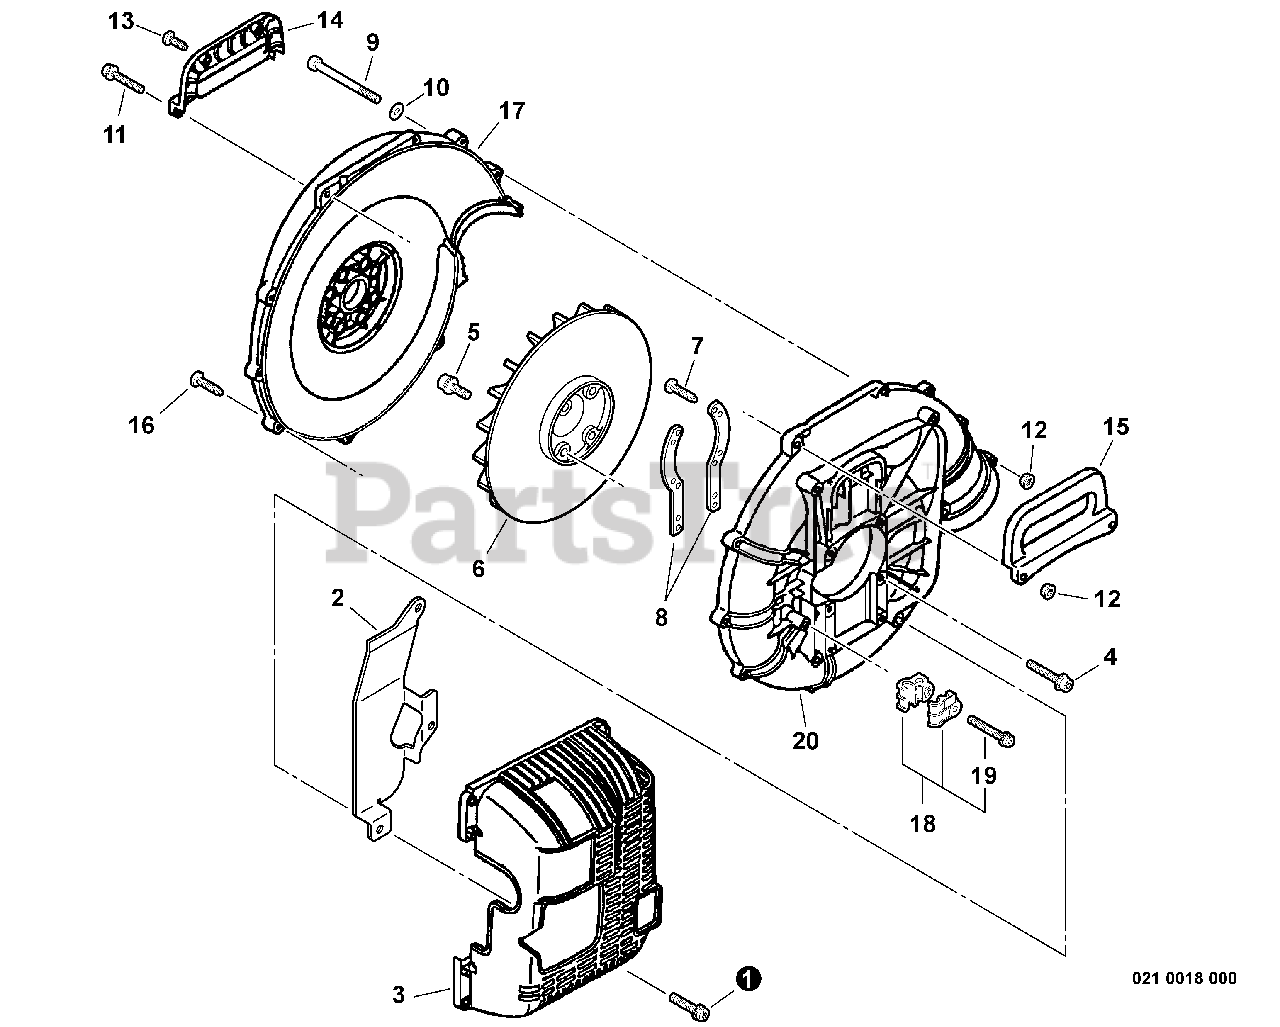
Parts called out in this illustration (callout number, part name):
1	SCREW 5×18
2	INSULATOR
3	COVER, ENGINE
4	SCREW 5×32
5	BOLT 5×20
7	SCREW TAPPING 3×12
8	BRACKET, ENGINE
9	BOLT 5×60
10	WASHER, FLAT 5.5×10×0.8
11	SCREW 5×45
12	NUT, FLANGE M5
13	SCREW 5×16
14	HANDLE
16	SCREW 5×30
17	COVER, FAN - INNER
18	CABLE HOLDER KIT
19	SCREW 5×25
20	COVER, FAN - OUTER
